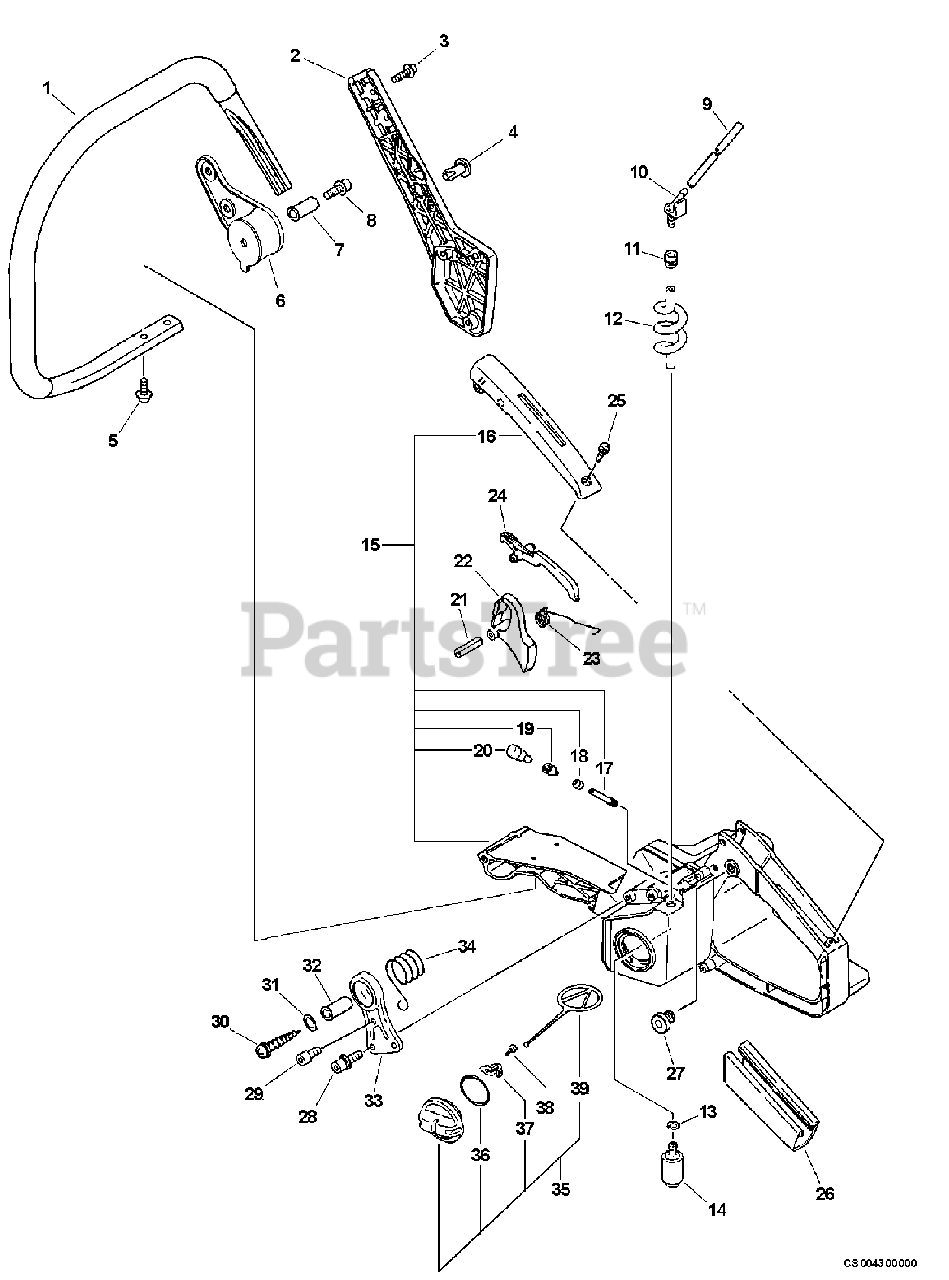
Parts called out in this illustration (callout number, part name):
1	HANDLE - FRONT
2	BRACKET, HANDLE
3	SCREW - 5X20
5	SCREW - 5X14
6	CUSHION
7	COLLAR - 5
8	SCREW - 5X20
9	PIPE - 3X6X110 -- BLACK
10	CONNECTOR, PIPE
11	GROMMET
12	PIPE - BLACK
13	CLIP - 6.5
14	FILTER, FUEL
15	HANDLE ASSY - REAR
16	COVER, HANDLE
17	PIPE - VENT
18	CLIP - 5.5
19	COVER, VENT
20	VENT, FUEL TANK
21	PIN - SPRING -- 5X25
22	TRIGGER, THROTTLE
23	SPRING, TRIGGER
24	LEVER, TRIGGER LOCKOUT
25	SCREW - 4X14
26	GRIP, HANDLE
28	SCREW - 5X14
29	SCREW - 5X8
30	SCREW - 5X35
31	WASHER - 5
32	COLLAR - 5
33	BRACKET, CUSHION
35	CAP ASSY
36	O-RING - 29
37	RETAINER
38	SCREW - 3X8
39	CONNECTOR, CAP
